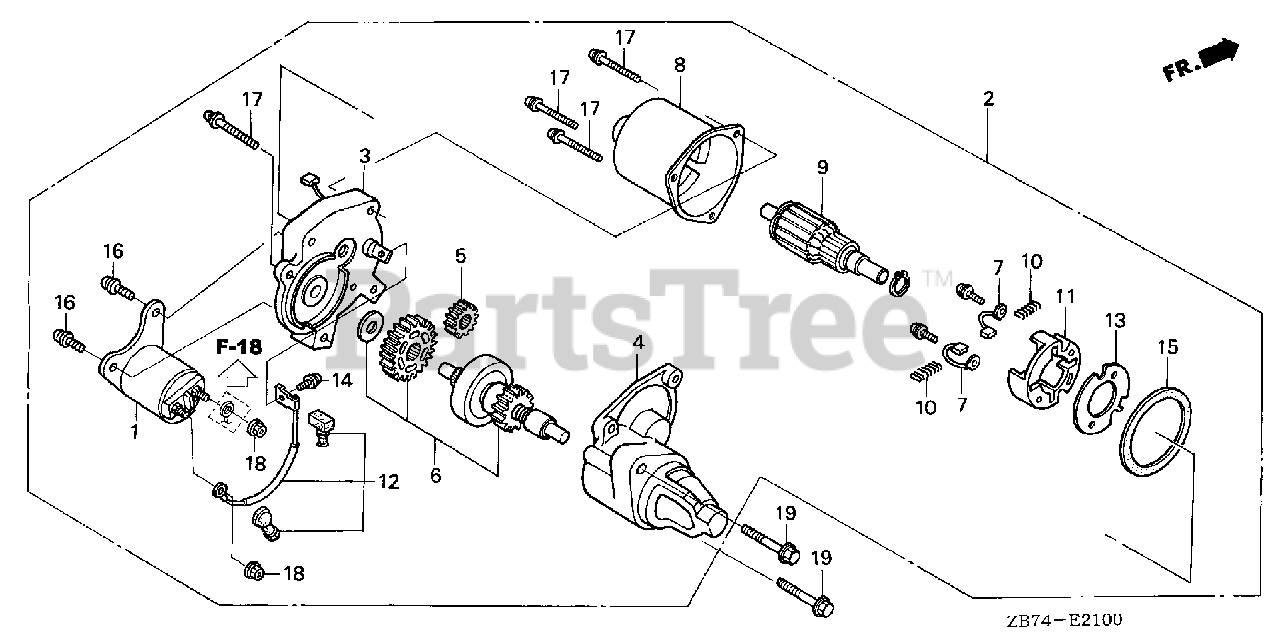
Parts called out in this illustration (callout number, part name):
1	CONTACTOR ASSY.
2	STARTER MOTOR UNIT
3	BRACKET, CENTER
4	BRACKET, FR.
5	GEAR, DRIVE PINION
6	CLUTCH, OVERRUNNING
10	SPRING, BRUSH RETURN
11	HOLDER, BRUSH
12	WIRE, WATER COVER
14	SCREW-WASHER (4X6)
16	SCREW-WASHER (5X14)
17	SCREW-WASHER (5X32)
18	NUT-WASHER (6MM)
19	BOLT, FLANGE (8X40)
